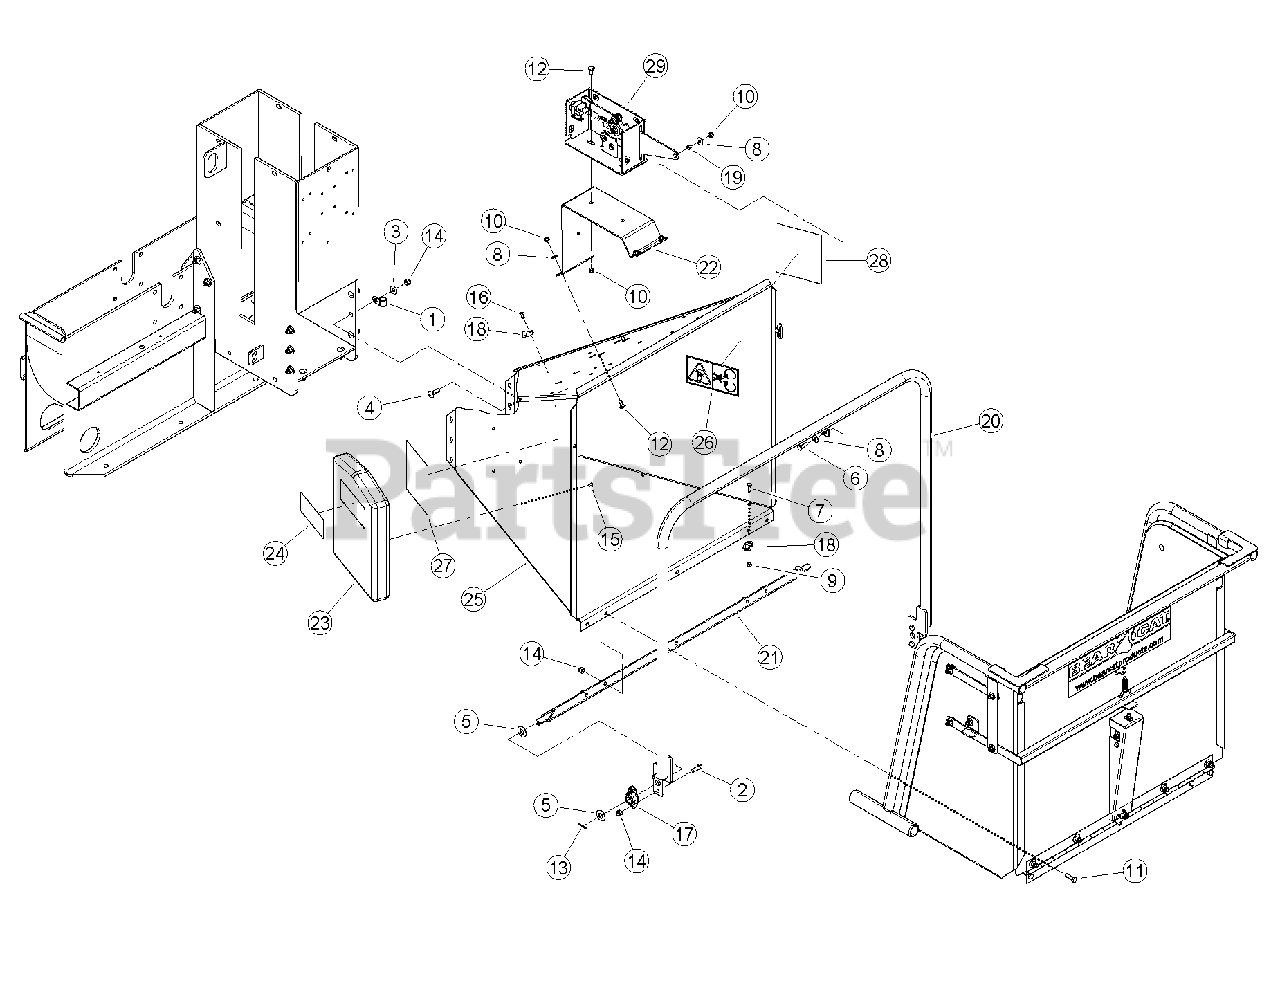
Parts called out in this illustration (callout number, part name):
1	CLAMP, 9/16 COATED
2	BOLT, 3/8 X 1 HEX HD GR5 ZP
3	WASHER, 3/8 FLAT ZP
4	BOLT, 3/8 X 1-1/2 CRG GR5 NC ZP
5	WASHER, 5/8 SAE FLAT ZP
6	BOLT, 5/16 X 1 HHCS GR5 NC ZP
7	BOLT, 1/4 X 1 CRG GR5 NC ZP
8	WASHER, 5/16 FLAT ZP
9	NUT, 1/4 NE NYLOCK ZP
10	NUT, 5/16 NE NYLOCK ZP
11	BOLT, 3/8 X 1-1/4 HEX HD GR5 ZP
12	BOLT, 5/16 X 3/4 CRG GR5 NC ZP
13	PIN, 1/8 X 1.00 ZP COTTER
14	NUT, 3/8 NE NYLOCK ZP
15	RIVET, AL BLIND 1/4 X 1/2 DOME HEAD
16	RIVET, AL BLIND 1/4 X 3/4 DOME HEAD
17	BEARING, SIDE FLANGE MOUNT, 5/8
18	CLAMP, CABLE MOUNT
19	SPACER, IDLER PIVOT
20	WELDMENT, CONTROL ARM
21	WELDMENT, CONTROL PIVOT
22	MOUNT, SWITCH BOX
23	ASSEMBLY, MANUAL CONTAINER SERVICE PART
24	DECAL, MUTILINGUAL MANUAL
25	ASSEMBLY, BIG CHIPPER CHUTE SERVICE PART
26	DECAL, BLADE DANGER ISO
27	DECAL, FEED POSITION
28	DECAL, FEED POSITION
29	ASSEMBLY, SWITCH BOX
